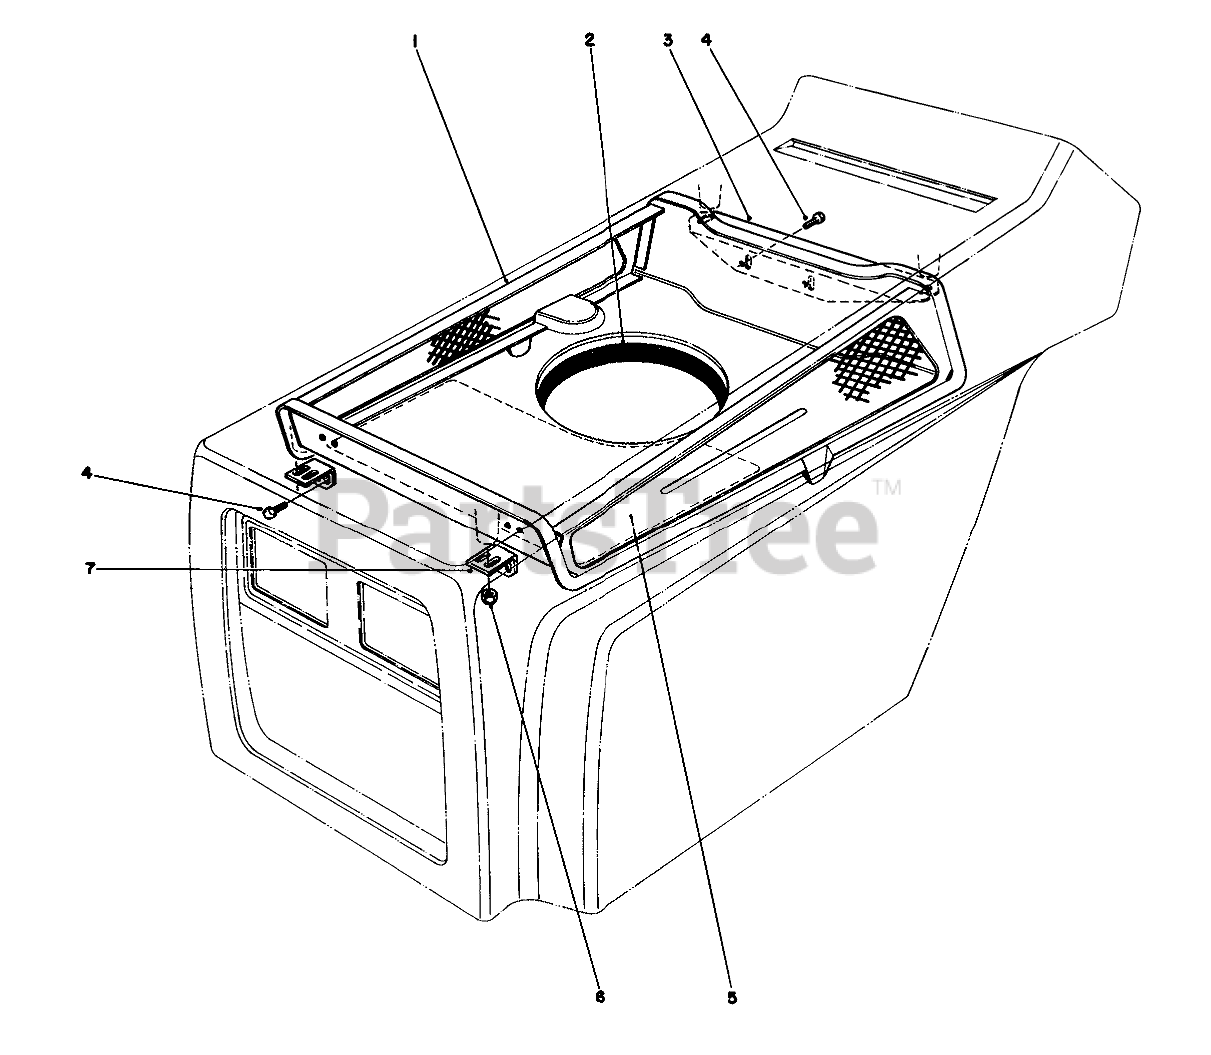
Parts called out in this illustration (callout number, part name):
1	Duct Hood
2	Seal Engine
3	Bracket Rear Duct Support
4	SCREW-HWHTF
5	Decal Service
6	NUT-LOCK, NI
7	Bracket Front Duct Support
